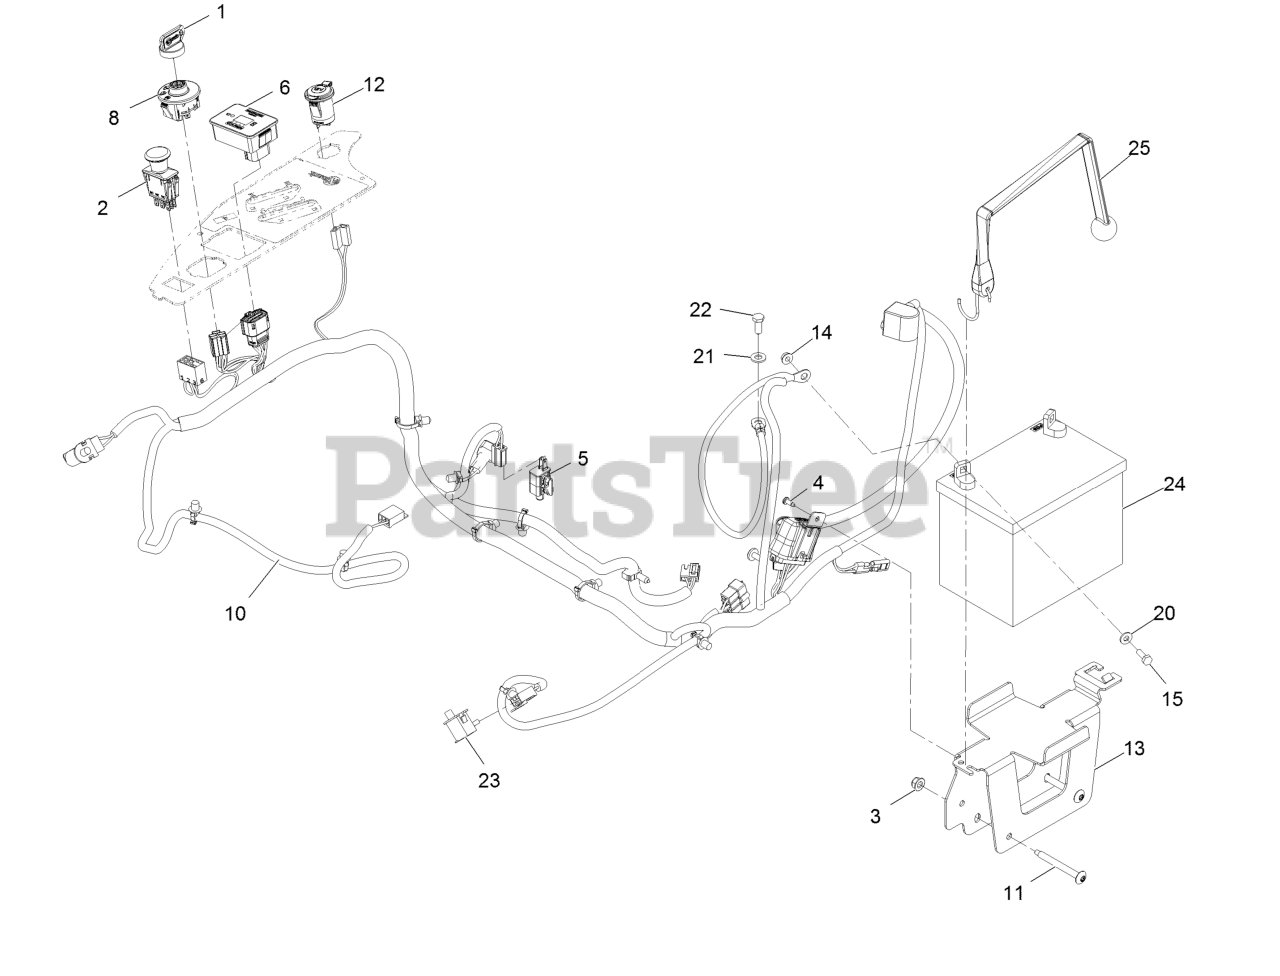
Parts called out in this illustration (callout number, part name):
1	Key-Ignition
1	Key-Exmark Logo
2	Switch-PTO
3	Nut-Nyloc 5/16-18 Flg
4	Screw-Tph #10-24 X 1/2 Tf
6	Module ASM
8	Switch-Ignition
10	Harness-Wire
11	Screw-Truss HD 5/16-18 X 2 3/4 Torx Plus
12	Port-Power, 12V
13	Tray-Battery
14	Nut-Whizlock 1/4-20
15	Screw-HH 1/4-20 X 3/4
20	Washer-1/4 SAE
22	Screw-HH M8-1.25 X 20Mm
24	Battery (300 CCA, Wet)
25	Strap-Bungee
